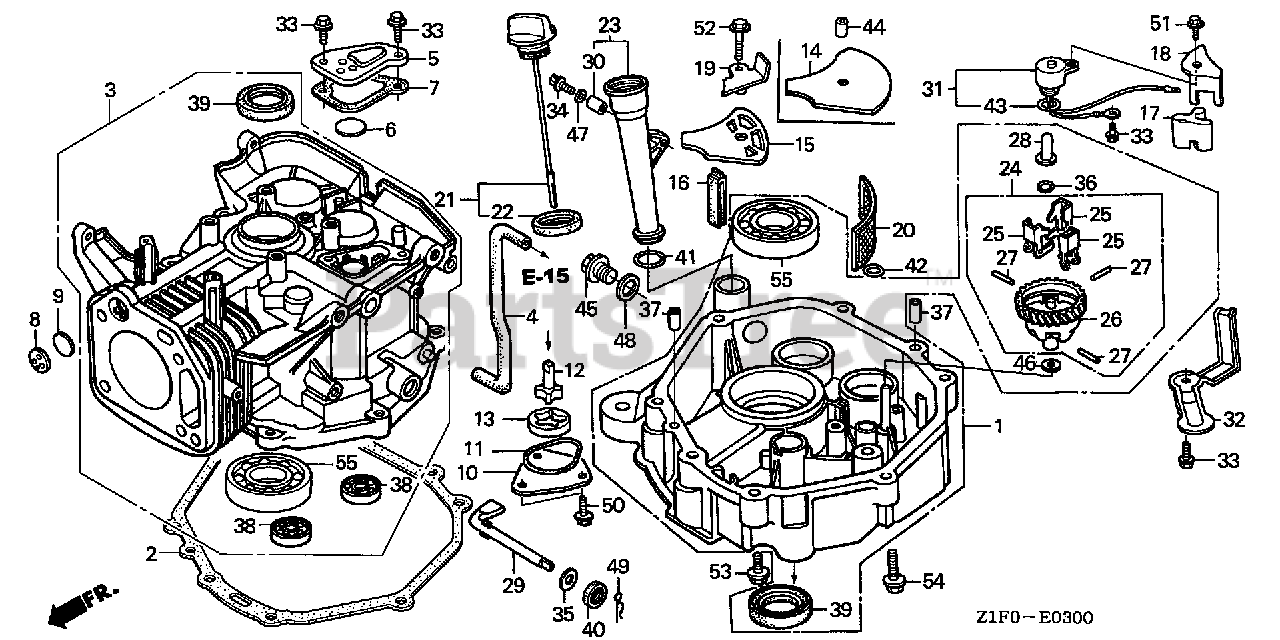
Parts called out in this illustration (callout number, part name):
1	PAN ASSY., OIL
2	GASKET, OIL PAN
3	CYLINDER ASSY.
4	TUBE, BREATHER
5	CAP, BREATHER CHAMBER
6	VALVE, BREATHER
7	GASKET, BREATHER CAP
8	PLATE, ONE-WAY VALVE
9	VALVE, ONE-WAY
10	COVER, OIL PUMP
11	O-RING, PUMP COVER
12	ROTOR (INNER)
13	ROTOR, OIL PUMP (OUTER)
15	PLATE, OIL FILTER
16	RUBBER, OIL RETURN
17	STOPPER, OIL
18	PLATE, OIL STOPPER
19	PLATE, SUCTION
20	SCREEN, OIL FILTER
21	CAP ASSY., OIL FILLER
22	GASKET, OIL FILLER CAP
23	EXTENSION, OIL FILLER
24	GOVERNOR ASSY.
25	WEIGHT, GOVERNOR
26	HOLDER, GOVERNOR WEIGHT
27	PIN, GOVERNOR WEIGHT
28	SLIDER, GOVERNOR
29	SHAFT, GOVERNOR ARM
30	COLLAR, EXTENSION Use up to Engine SN 1257294.
31	SWITCH, OIL LEVEL
32	PROTECTOR, SWITCH
33	BOLT, FLANGE (6X12) (CT200)
34	BOLT, FLANGE (6X35)
35	WASHER, THRUST (8.1MM)
36	CLIP, GOVERNOR HOLDER
37	PIN, DOWEL (8X12)
38	BEARING, RADIAL BALL (6202)
39	OIL SEAL (35X52X8) (NOK)
40	OIL SEAL (8X14X5)
41	O-RING (22.5X2.2) Use from Engine SN 1257295.
42	O-RING (11.8X2.4)
43	O-RING (11.8X2.4)
45	BOLT, DRAIN PLUG (20MM)
46	WASHER, PLAIN (6MM)
47	WASHER, PLAIN (6MM)
48	WASHER, DRAIN PLUG (20MM)
49	PIN, LOCK (10MM)
50	BOLT, FLANGE (6X12) Use up to Engine SN 1543277.
51	BOLT, FLANGE (6X16) Use from Engine SN 2056820.
52	BOLT, FLANGE (6X25)
53	BOLT, FLANGE (8X40)
54	BOLT, FLANGE (8X60)
55	BEARING, RADIAL BALL (6207)
